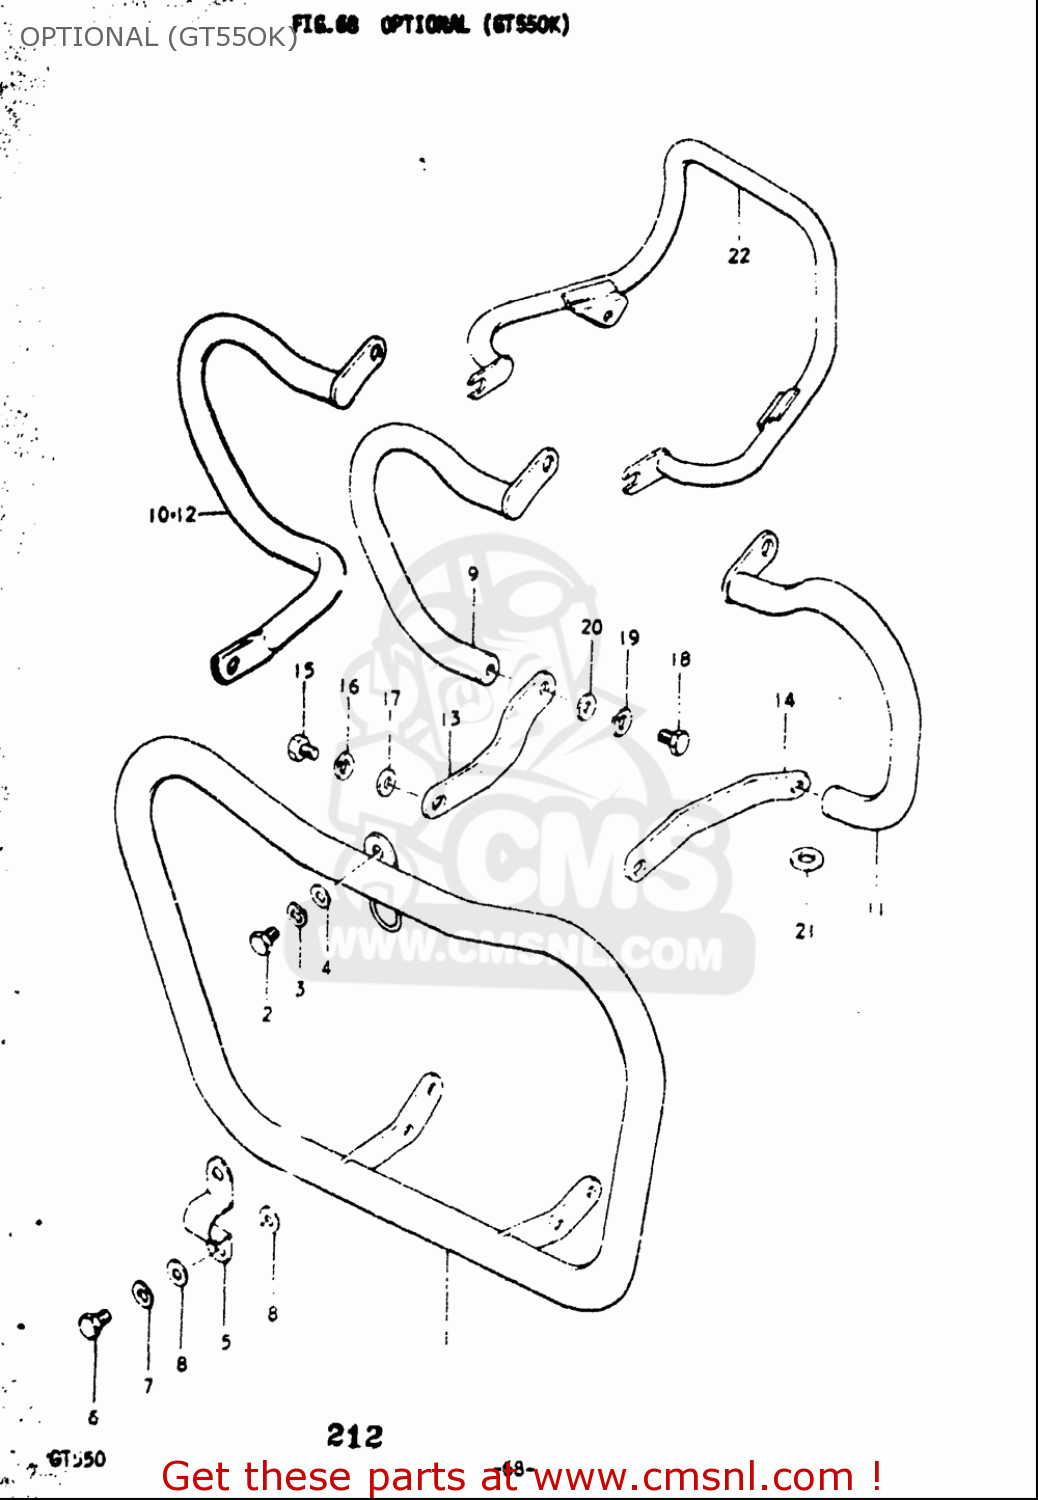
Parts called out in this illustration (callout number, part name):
2	BOLT
3	WASHER,LOCK
4	WASHER
6	BOLT
7	WASHER,LOCK
8	WASHER
14	BOLT
15	WASHER,LOCK
16	WASHER
17	BOLT
18	WASHER,LOCK
19	WASHER
20	WASHER(12.5X24X3.2)
